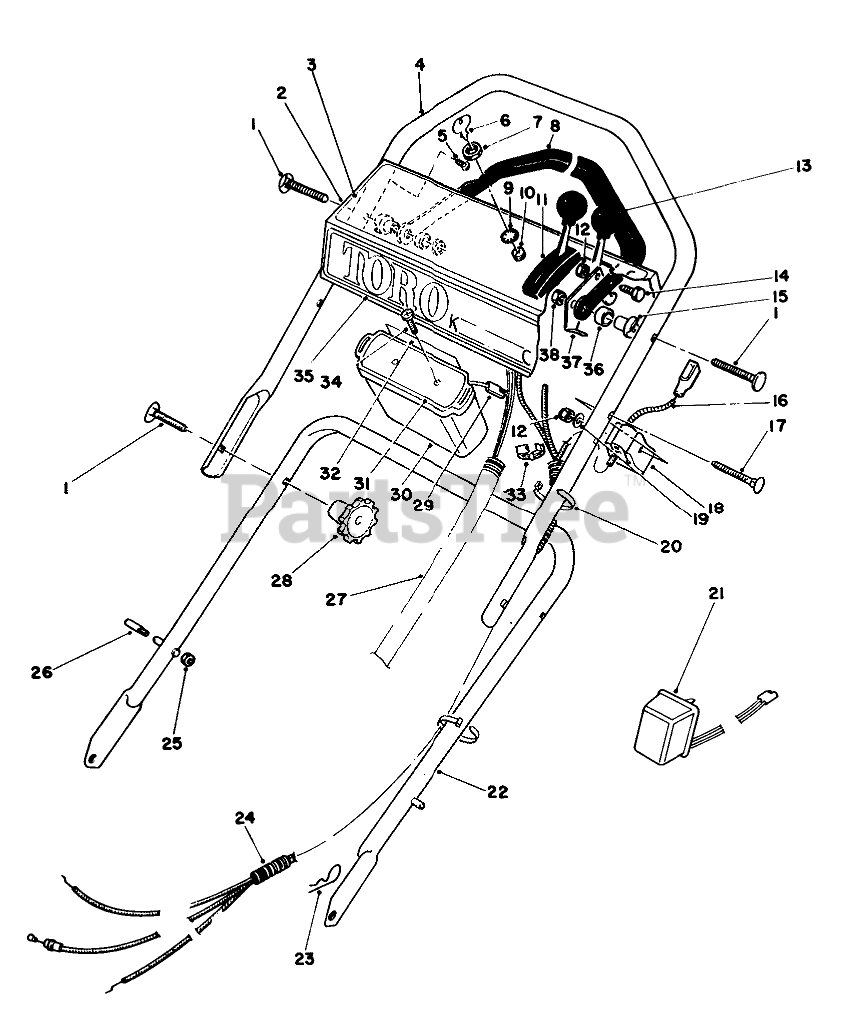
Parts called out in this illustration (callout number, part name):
1	5/16-18 X 2 HNDLE SCREW
2	Control Panel (Incl. Ref. #3)
3	INSTRUCTION DECAL
4	Handle-Upper
5	SCREW-HWHTF
6	Key
7	NUT-HH
8	Bar-Control
9	WASHER-TOOTH, INTERNAL
10	Switch-Starter (Incl. Ref. #7 & 9)
11	SERVICE TRACT. CONTROL
13	SERVICE THROTTLE CONTRO
14	SCREW-HH
15	SPACER-SUPPORT
16	Brake Cable
17	SCREW-HANDLE
18	SUPPORT-CABLE
19	WASHER-FLAT
20	TIE-CABLE
21	Charger
22	LOWER HANDLE ASM
23	PIN-COTTER, HAIR
24	CONT. CABLE COVER
25	Locknut
26	HANDLE PIN
27	WIRE HARNESS
29	LEAD WIRE ASM
30	Battery Case
31	BATTERY COVER
32	Decal
33	FITTING-RING
35	Decal-Toro
36	SPACER-NYLON
37	Lever-Control
38	NUT-LOCK, NI
